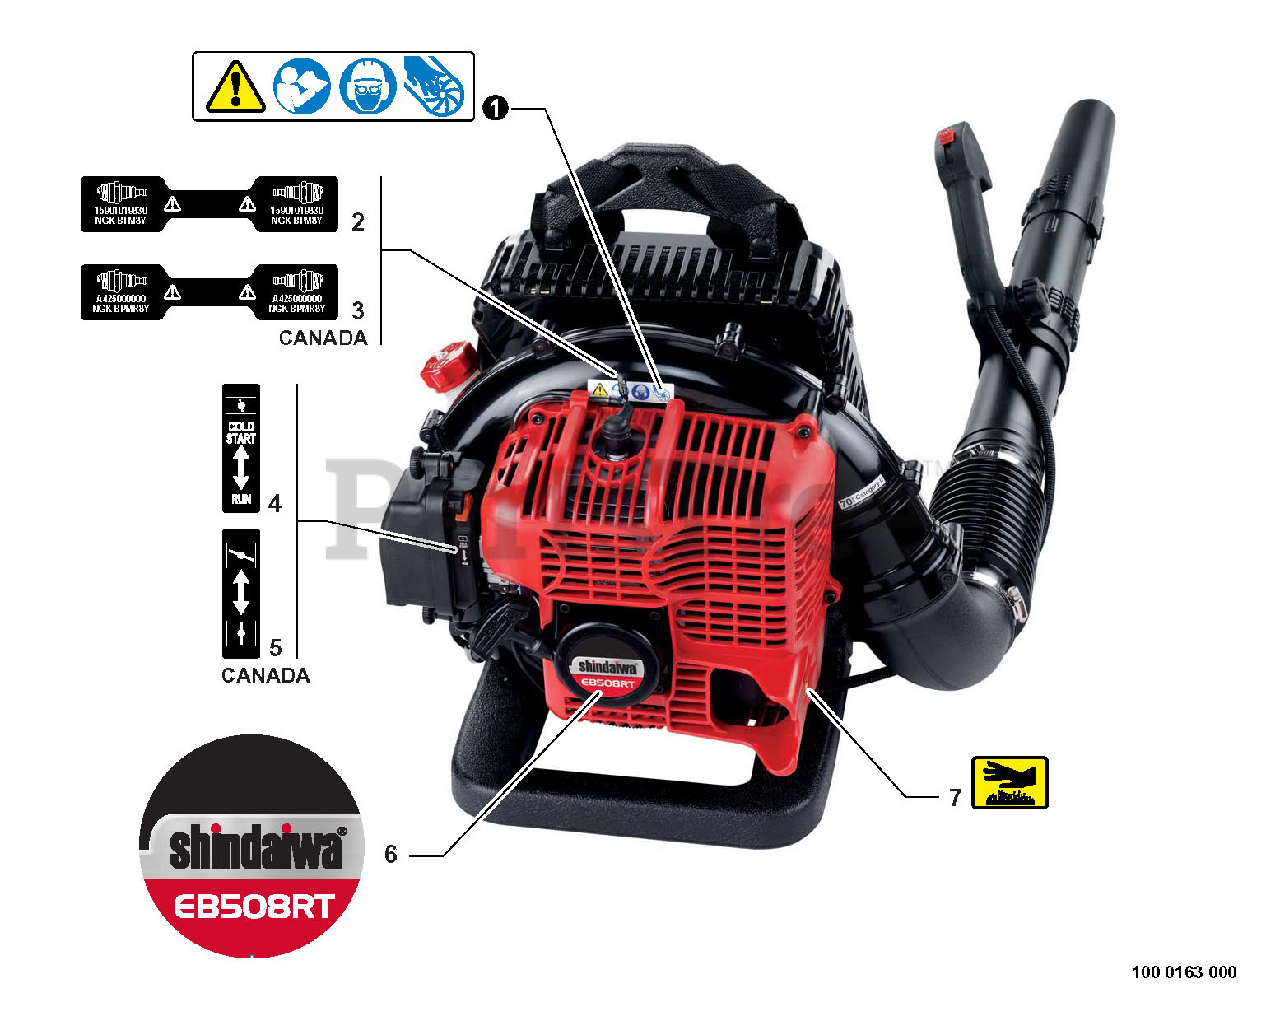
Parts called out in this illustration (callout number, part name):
1	LABEL - CAUTION
2	LABEL - SPARK PLUG -- BPM-8Y
3	LABEL - SPARK PLUG -- BPMR-8Y
4	LABEL - CHOKE
5	LABEL - CHOKE
6	LABEL - MODEL EB508RT
7	LABEL - HOT SURFACE
